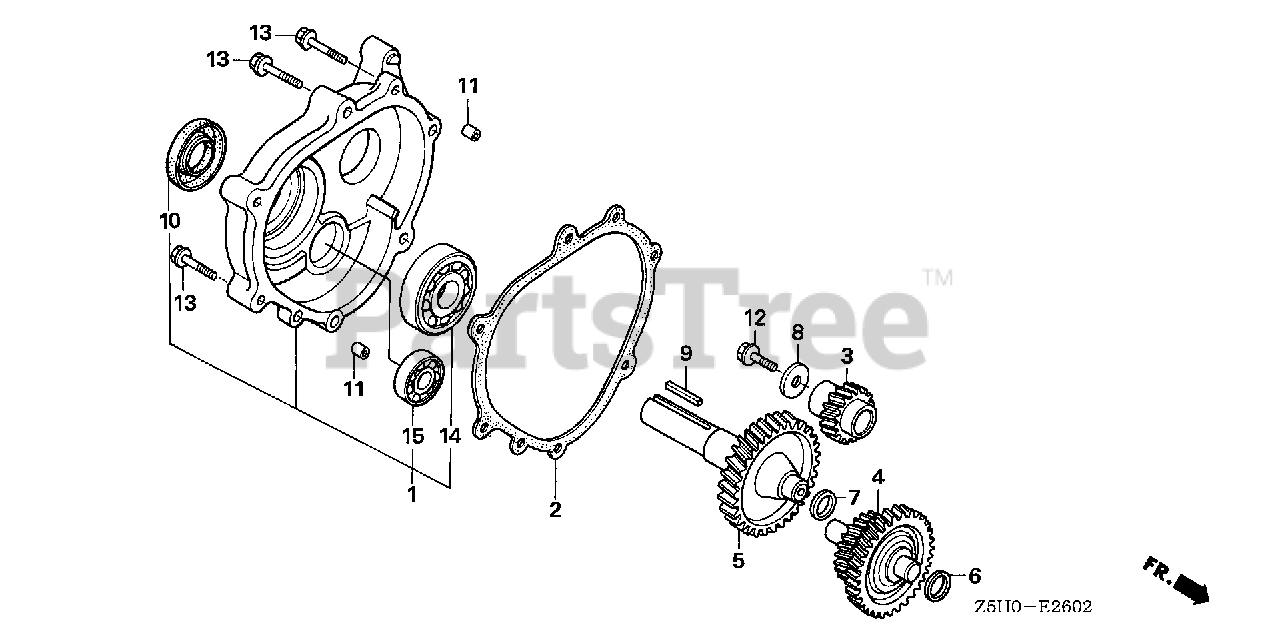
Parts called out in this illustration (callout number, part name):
1	COVER ASSY., REDUCTION CASE
2	GASKET, CHAIN CASE COVER
3	GEAR, PRIMARY DRIVE (17T)
4	COUNTERSHAFT
5	SHAFT, P.T.O. (H-TYPE)
6	SHIM A
7	SHIM B
8	WASHER (8MM)
9	KEY (6.3X6.3X43)
10	OIL SEAL (30X46X8)
11	PIN A, DOWEL (8X14)
12	BOLT, FLANGE (8X25)
13	BOLT, FLANGE (8X40) Use up to Engine SN 1003236.
14	BEARING, RADIAL BALL (6206)
15	BEARING, RADIAL BALL (6302)
